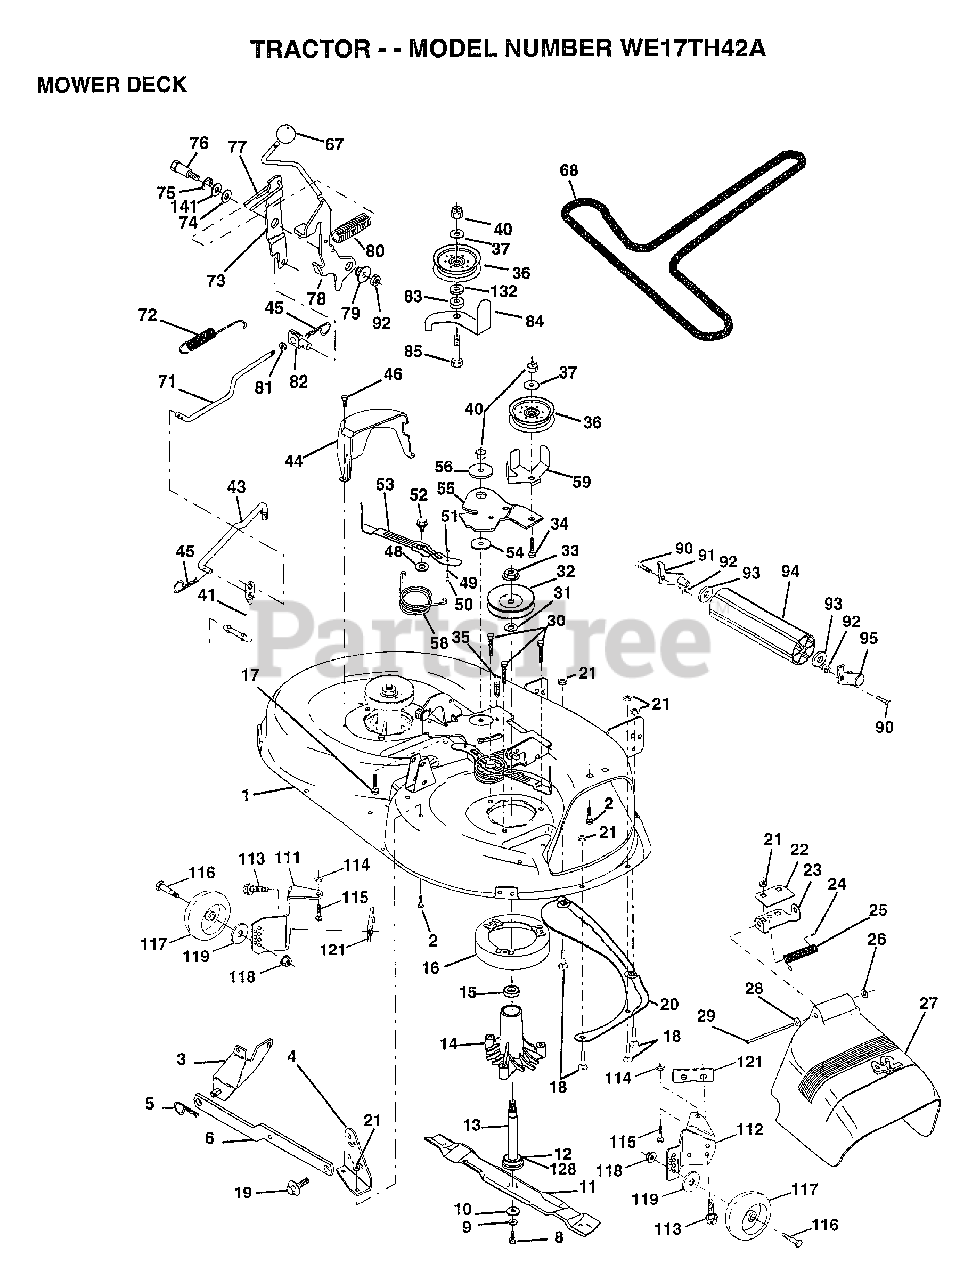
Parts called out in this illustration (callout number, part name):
1	"HOUSING ASSY.42"""
2	BOLT
3	BRKT ASM SWAY BAR
4	BRKT DECK SW BAR
8	BLADE BOLT
10	WASHER.HARD.BLADE
11	"BLADE.42"" HIPERF"
12	BEARING.BALL
14	HSG ASM MANDREL
15	BEARING
16	STRIPPER RND MWR
17	BOLT RDHD 3/8-16
18	BOLT
19	BOLT SHD 5/16-18
20	BAFFLE VORTEX 42
22	STIFFENER BRKT
23	DEFLECTOR BRKT
24	CAP-SLEEVE LT
25	SPRING TORSION
26	NUT PUSH M
27	DEFLECTOR.SHIELD
28	WASHER
29	HINGE ROD
30	"SCREW-THD ROLL,WA"
31	WASHER
32	PULLEY.MANDREL.42
34	BOLT
35	XMAS TREE FASTNER
36	FLAT IDLER PULLEY
37	WASHER
41	PIVOT ROD
43	ROD CLUTCH W/NIBS
44	GUARD MAND LH BLK
45	RETAINER M
46	SCREW.1/4-20X5/8
48	HARD SMALL WASHER
49	ROLLER ASM-CAM
50	SHOULDER BOLT
51	LOCKNUT
52	BOLT.SHLD.5/16-18
53	BRAKE PAD ARM ASM
54	HARDENED WASHER
55	ARM-IDLER
56	SPACER RETAINER
58	SPRING TORSN BRAK
59	GUARD IDLER TUV
67	KNOB.RD.7/16-14
68	BELT.V.T-PATH
71	ROD CLUTCH 38/42
72	RETURN SPRING
73	CLUTCH ARM SECOND
74	WASHER
75	RING
76	SHOULDER BOLT
77	SPRING KEEPER
78	LEVER.ASM.CLUTCH
79	BUSHING
80	SPRING.CLUTCH.MWR
81	NUT
82	TRUNION ADJ
83	WASHER
84	"KEEPER-BELT,FIXED"
85	BOLT
90	BOLT
92	NUT
93	WASHER
111	BRACKET.GWHL.LH.
112	BRACKET.GWHL.RH.
113	SCREW
116	BOLT M
117	WHEEL.GUAGE
118	LOCKNUT
119	WASHER
121	BRACKET.EXTRD.GWL
128	WASHER.FELT.
132	WASHER GT
141	WASHER .T
